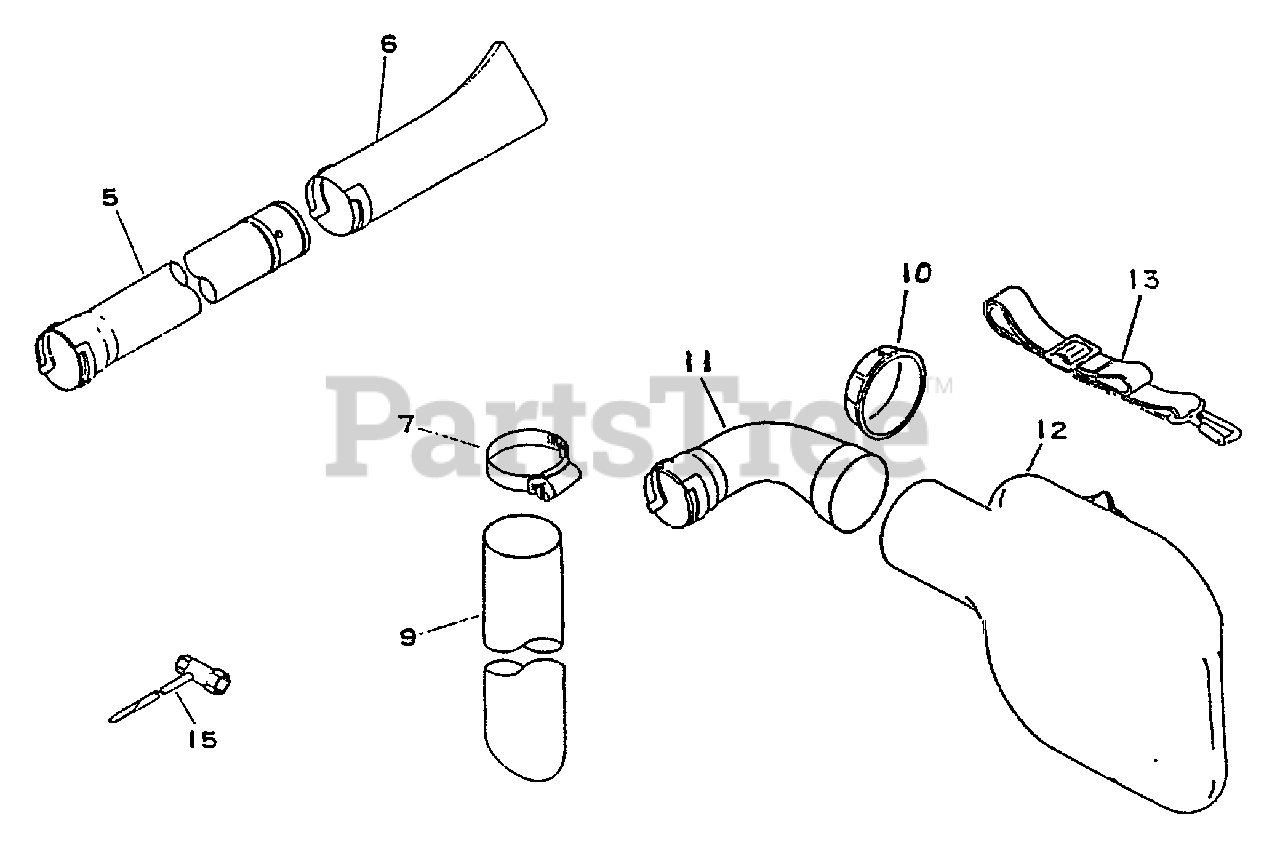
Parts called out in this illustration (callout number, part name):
5	TUBE, BLOWER - STRAIGHT
6	NOZZLE - FAN HEAD
9	TUBE, VACUUM
11	TUBE, DEBRIS
12	BAG, DEBRIS
13	SHOULDER STRAP ASSY
15	T-WRENCH
